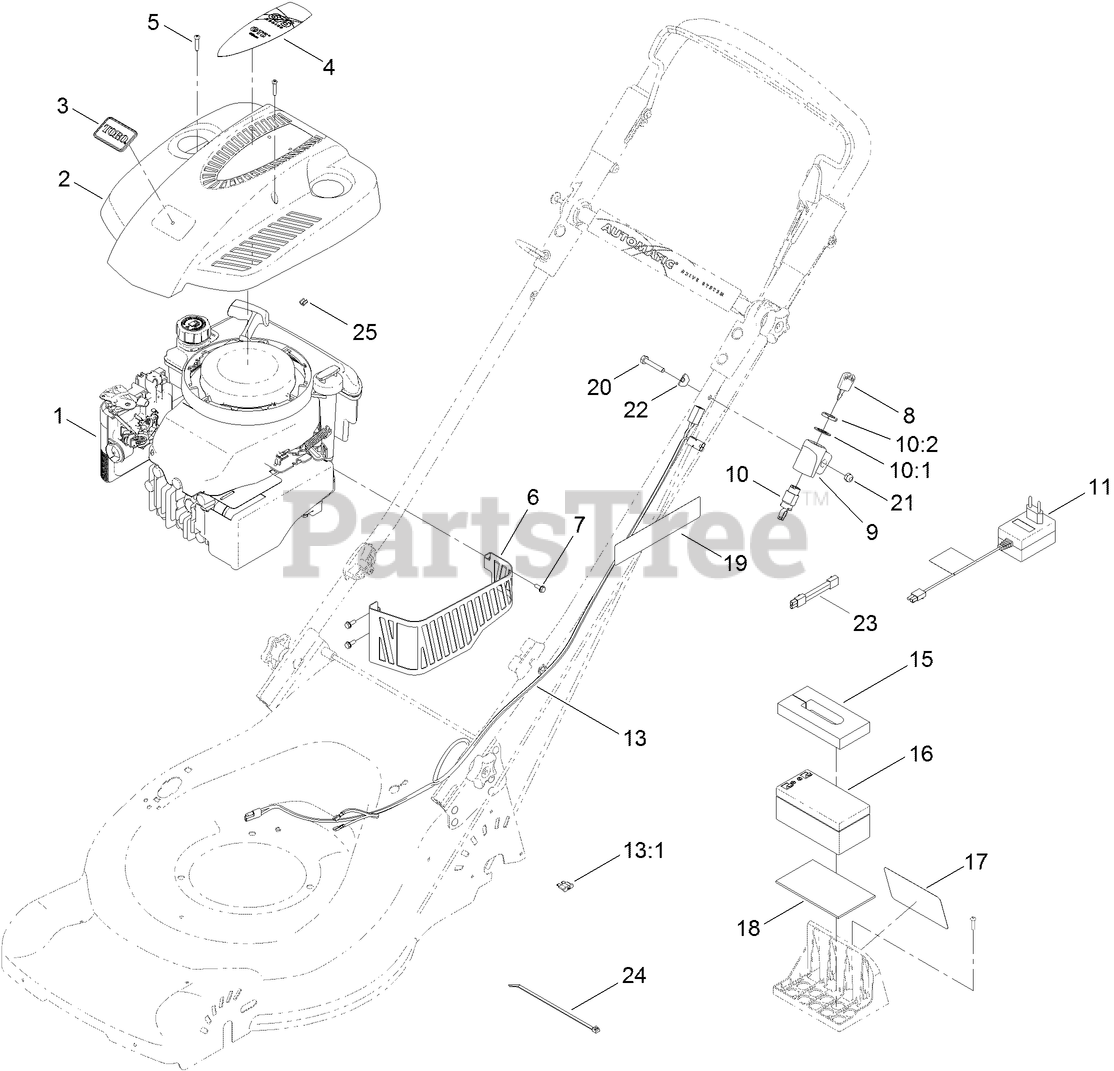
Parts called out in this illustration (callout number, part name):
2	SHROUD-ENGINE
3	PLATE-LOGO
4	DECAL-ENGINE, 48CM
5	SCREW-PPH
6	SHIELD-MUFFLER
7	SCREW-TAPTITE
9	MOUNT-SWITCH
10	STARTER SWITCH ASM
10:1	WASHER-LOCK
10:2	NUT-HH
11	CHARGER-EUROPEAN, 12V DC
13	HARNESS-WIRE, WPM
13:1	FUSE-40 AMP
15	FOAM-BLOCK
16	BATTERY-WET
17	DECAL-FUSE
18	FOAM-BATTERY
19	DECAL-WARNING
20	SCREW-HH
21	NUT-LOCK, NI
23	ADAPTER-CHARGER
24	TIE-CABLE
25	STOP-ROPE
